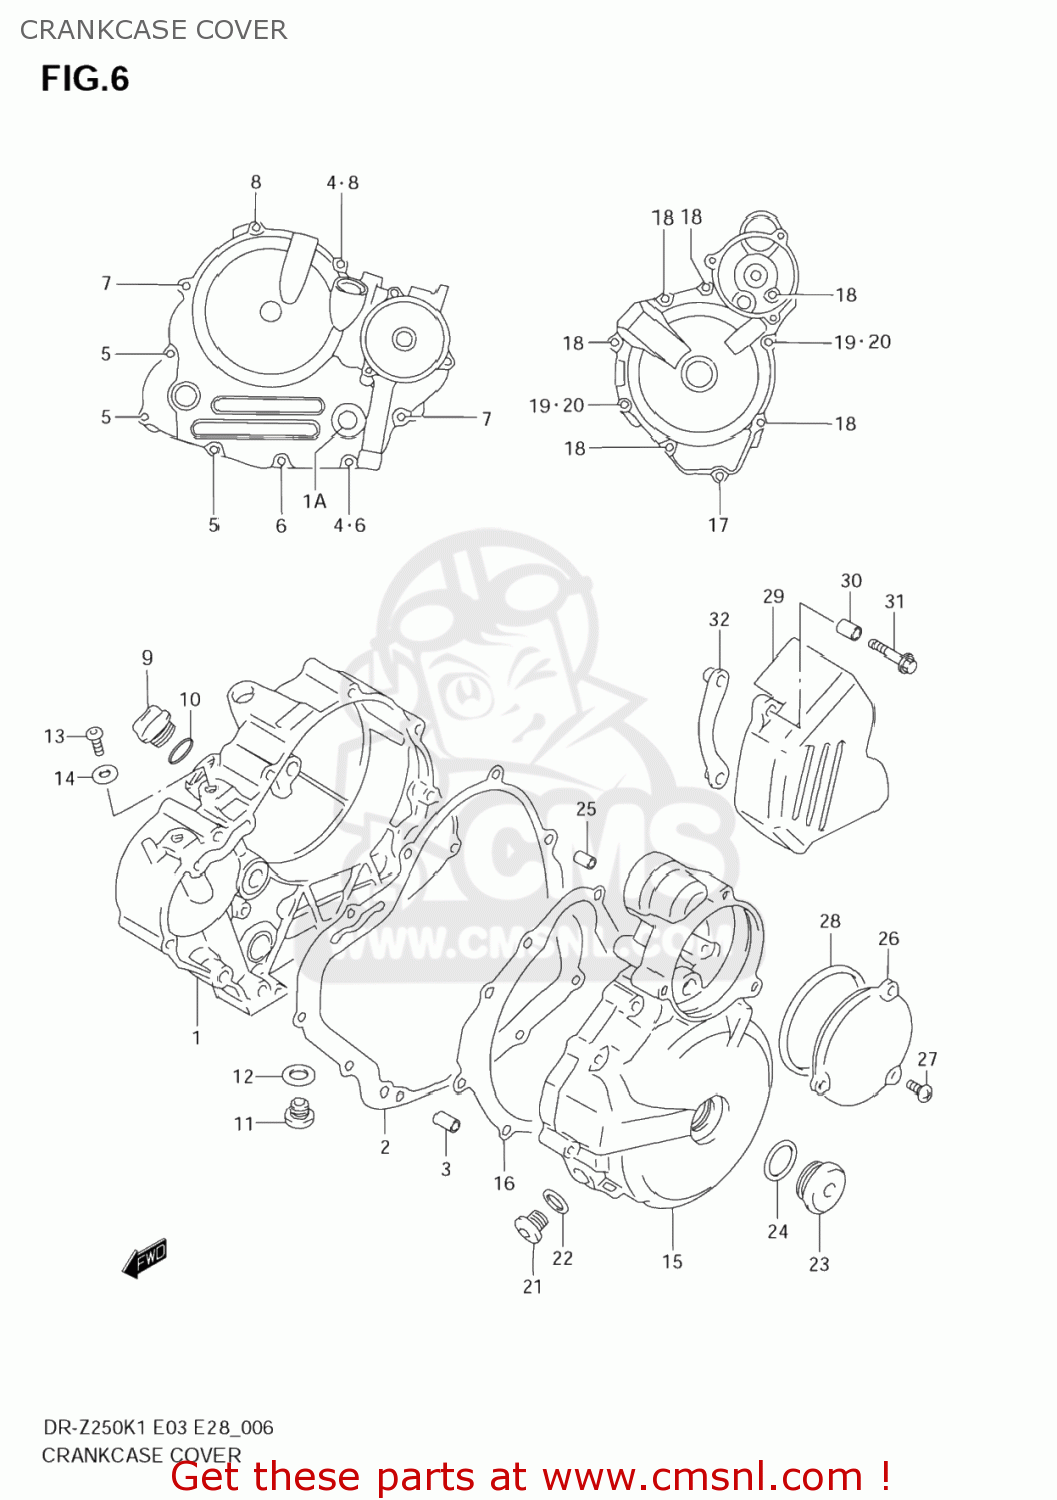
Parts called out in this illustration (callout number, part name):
1	COVER,CLUTCH
1A	LENS,OIL LEVEL CHECK
2	GASKET,CLUTCH COVER
3	PIN
4	GASKET(5.8X13X1.2) (NAS)
5	SCREW
6	BOLT
7	BOLT
8	BOLT
9	PLUG
10	O RING(D:3.1,ID:16.8)
11	PLUG
12	GASKET(13.8X18.8X4.8) (NAS)
13	PLUG(10X10)
14	GASKET(10X14X3.6) (NAS)
15	COVER,MAGNETO
16	GASKET,MAGNETO COVER
17	SCREW
18	BOLT
19	BOLT
20	GASKET(5.8X13X1.2) (NAS)
21	PLUG
22	GASKET(13.8X18.8X4.8) (NAS)
23	PLUG(26X9)
24	O RING(D:3.1,ID:22.7)
25	PIN
26	COVER,STARTER IDLE GEAR
27	SCREW 6X12
28	O RING(D:2.6,ID:69.6)
29	COVER,ENGINE SPROCKET
30	SPACER(6.5X10X11.5)
31	BOLT
32	PLATE,FR CHAIN GUIDE
